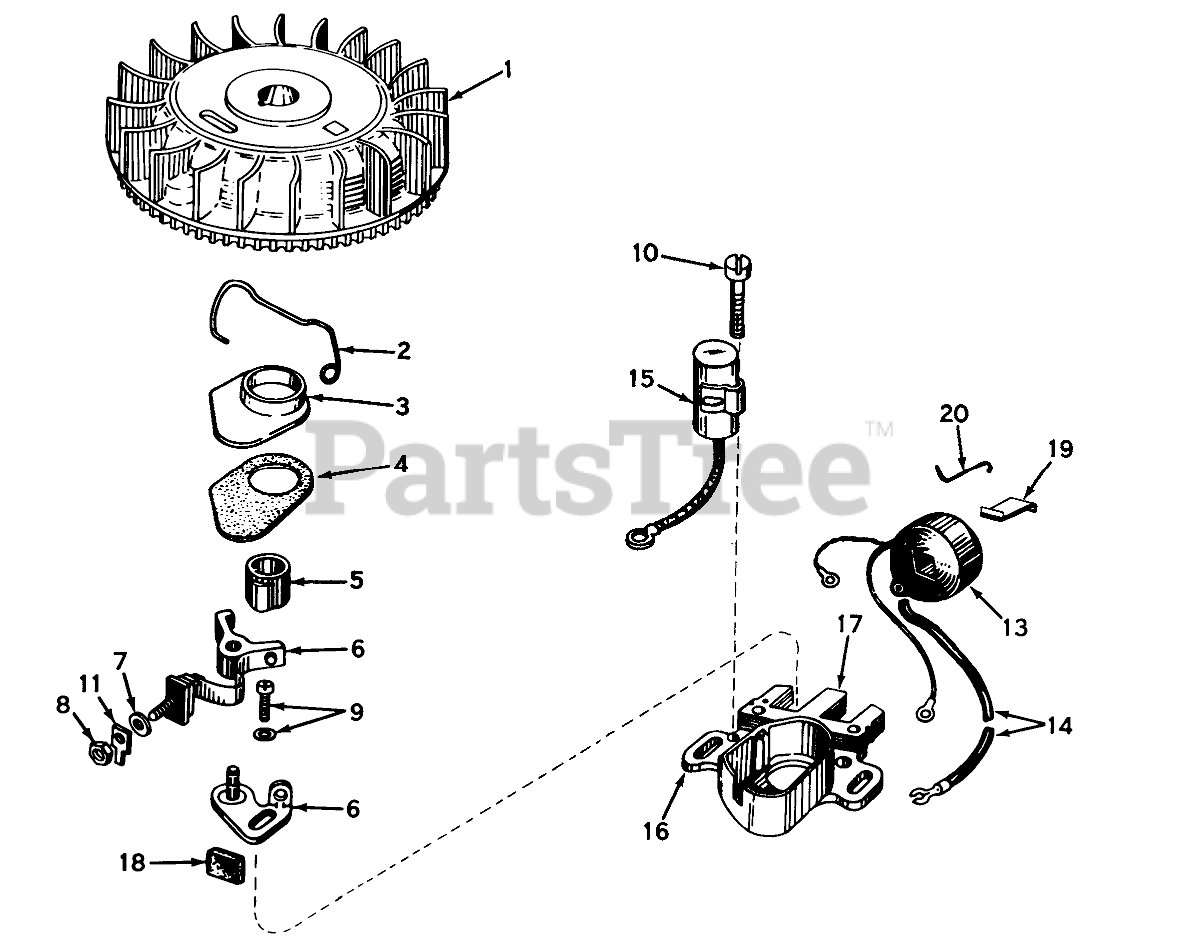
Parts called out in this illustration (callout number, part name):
1	Flywheel
2	Spring Breaker Box
3	Cover, Dust
4	Gasket Dust Cover
5	Cam, Breaker
6	Breaker Assy.
9	Breaker Screw
10	Condenser Screw
11	Terminal
13	Coil Assy. (Incl. Ref. Nos. 14, 15 & 19)
14	Wire, Lead
15	Condenser
16	Core & Plate
17	Stator Assy. (Incl. Nos. 2, 3, 5 thru 14 & 16 thru 19)
18	Felt,Cam Wiper
19	Spring Coil Wedge
20	Clip, Coil
